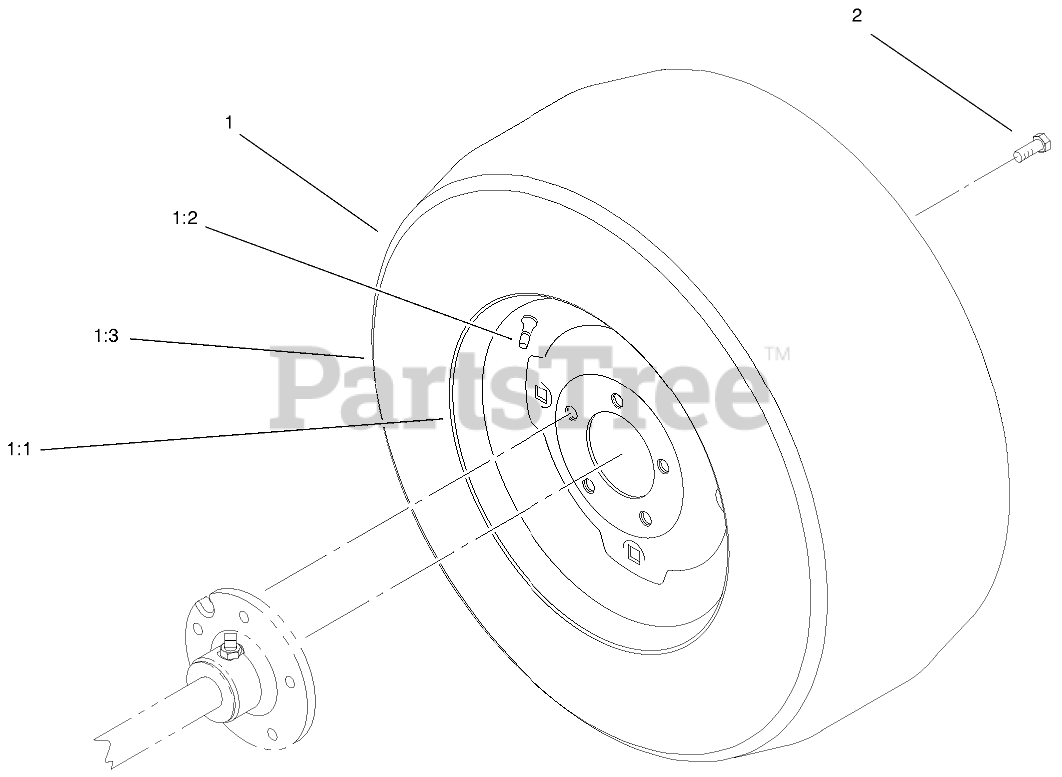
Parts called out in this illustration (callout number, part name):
1	ASM - WHEEL & TIRE
1:1	TIRE - 23 X 10.50-12
1:2	VALVE
1:3	RIM ASM
2	BOLT-LUG
